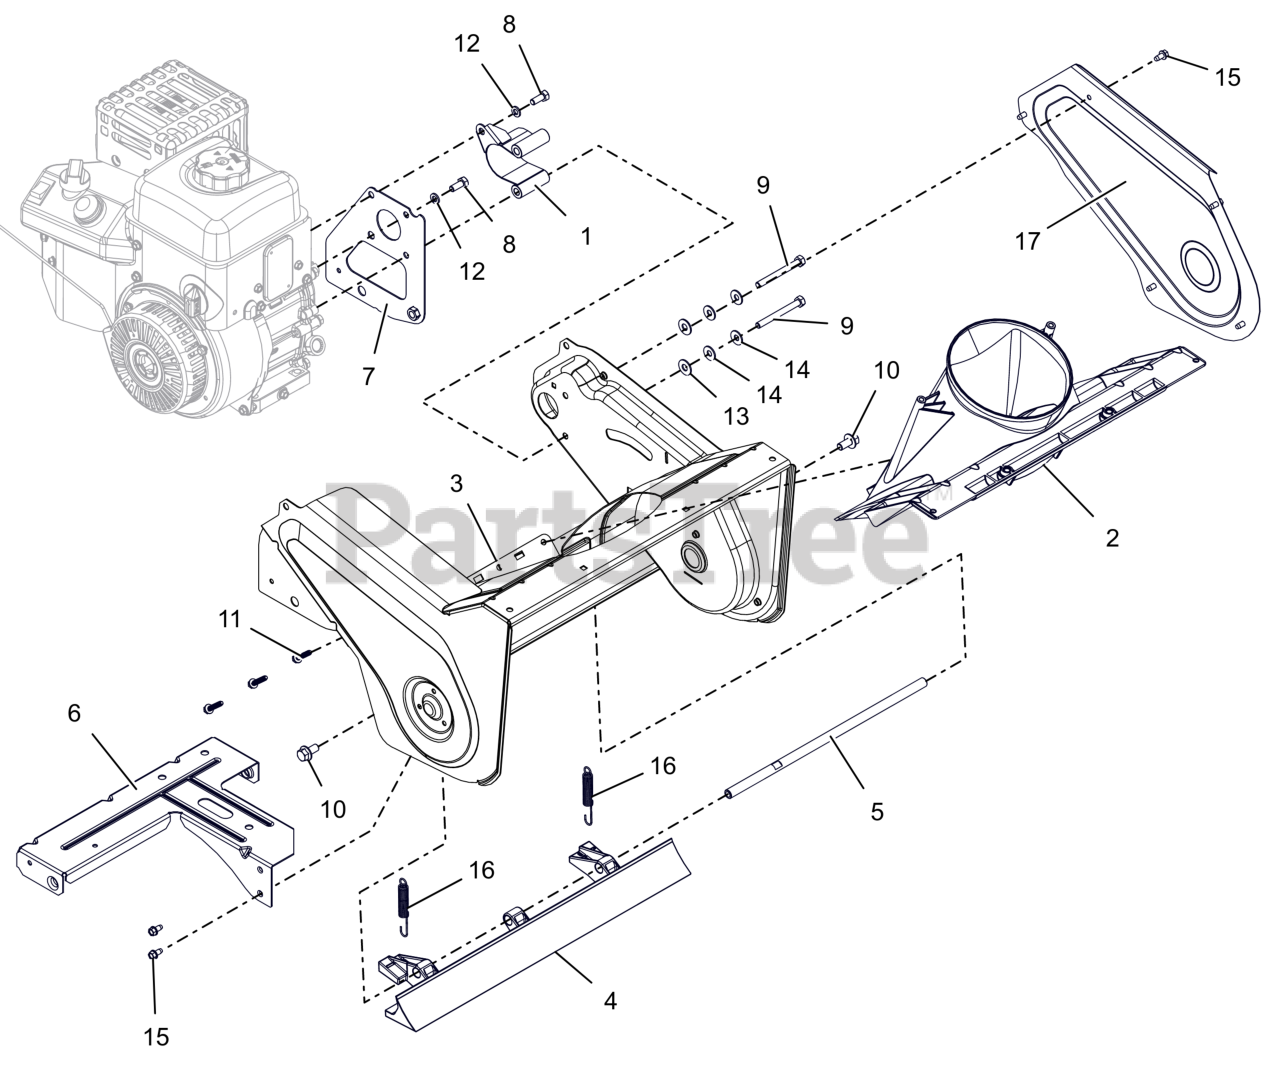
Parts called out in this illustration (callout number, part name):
1	FRAME, SPCR PTO
2	NECK, DISCHARGE
3	WLDMT, HOUSING - CSS
4	BLADE, SCRAPER - PIVOTING
5	ROD, PIVOT - SCRAPER
6	FRAME, ENGINE T-PLATE
7	FRAME, DRIVE BRACKET - WLMT
8	BLT, HEX .31-24X.750 G5ZCCEP30
9	BLT, HEX .31-24X3.00 G5 ZCC
11	SCR,PLASTITE .25-10X1.25 ZCC
12	WSHR,LK-REG .312X.078 ZCC
13	WSHR, HDND .375X.875X.064 ZCC
14	WSHR,BLVL-.322X.813X.063
15	SCR-TAP .25-20X.50 HWH ZCC
16	SPRING,EXT-.063 X .500 X 3.500
17	COVER, BELT DRIVE - HOUSING
